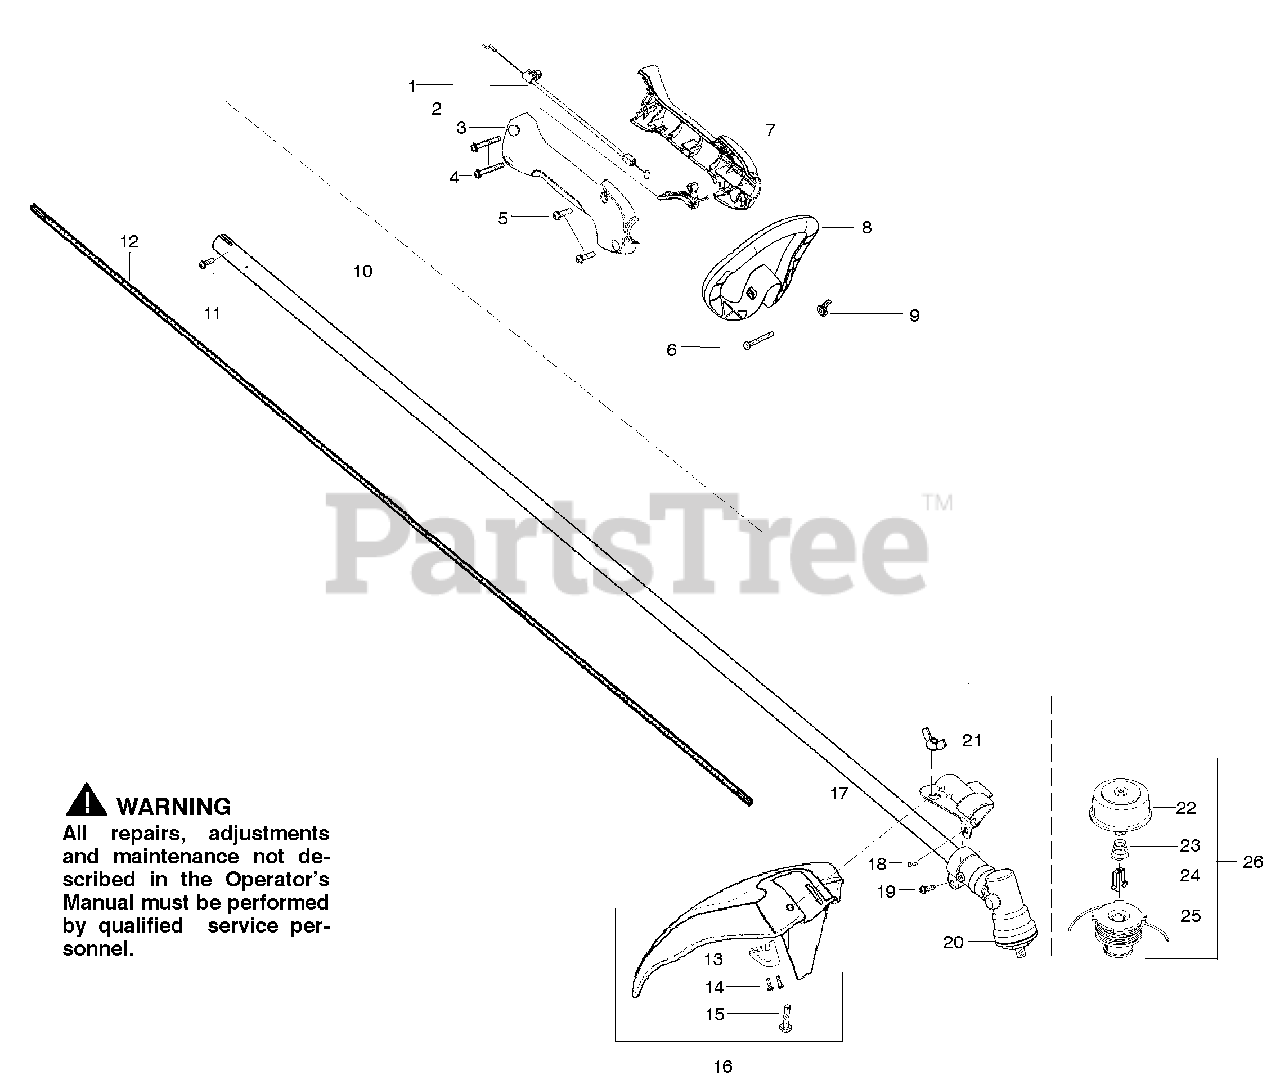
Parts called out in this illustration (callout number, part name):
1	Assy-Throttle Cable
3	Throttle Hsg. (Right)
6	Bolt-Handle
7	Throttle Hsg. (Left)
8	Handle-Assist
9	Wingnut-Handle
10	Assy-Drive Shaft Hsg.
11	Screw
12	Shaft- Flex
13	Line Limiter
15	Bolt-Shield
16	Kit-Shield Assy
17	Bracket-Shield
20	Assy-Gearbox
21	Wingnut
22	Assy-Hub.
24	Retainer
25	Accy-Spool w/Line
26	Accy-Head TNG VI Assy.
